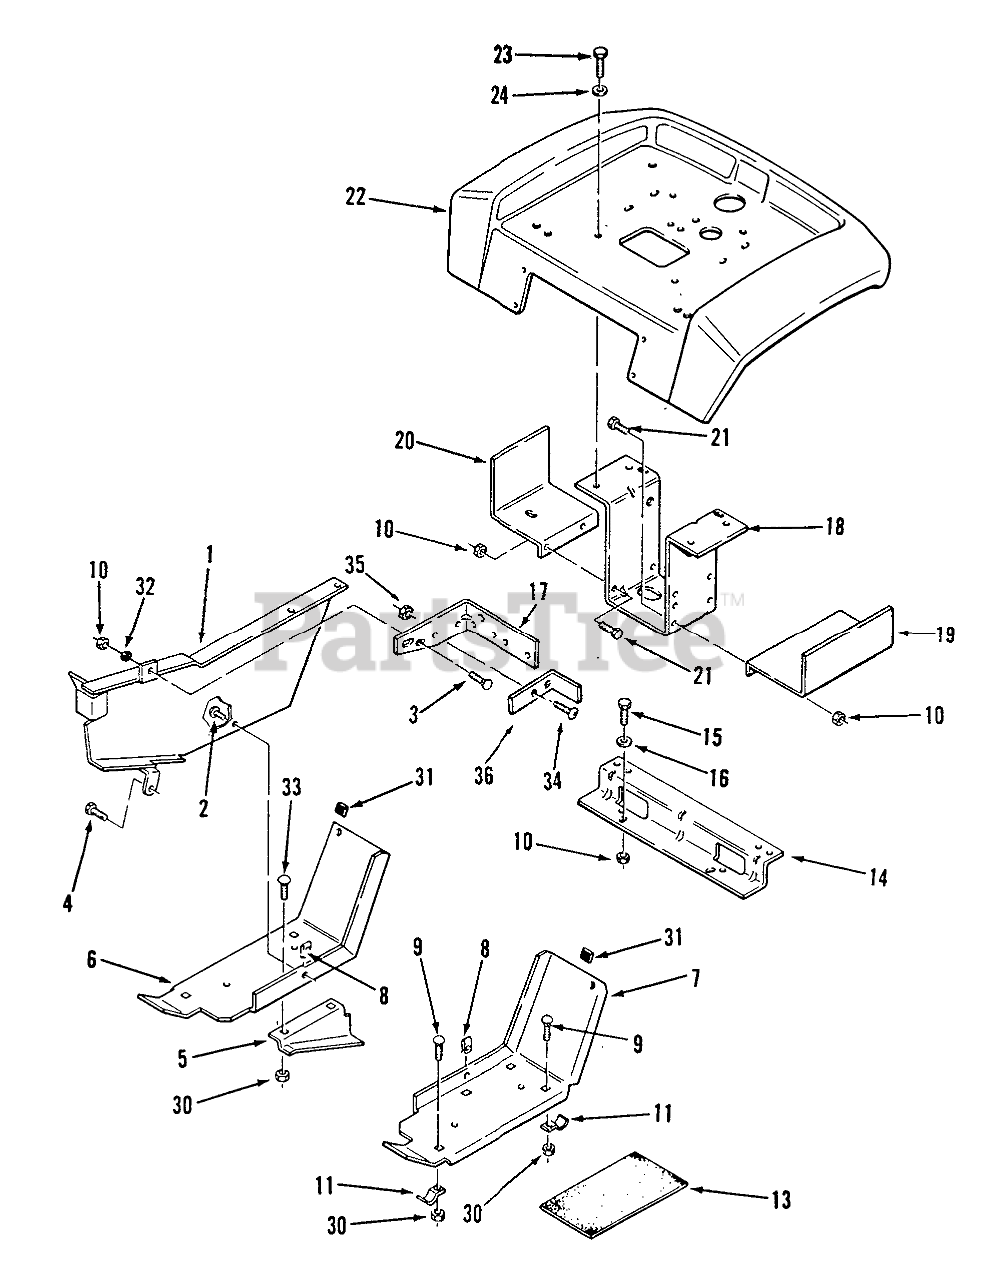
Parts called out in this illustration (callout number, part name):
1	ASSY-BELT GUARD 8 R
2	Screw
3	Bolt
4	SCREW
5	GUID-LOWER BLTR
6	Footrest-RH
7	FOOTREST LH R
9	Bolt
10	Nut
11	BRACKET
13	PAD FOOTREST
14	BRACKET-FENDER B
15	Bolt
16	WASHER 5/16 SAE
17	SUPPORT-BELT GUAR B
18	Bracket-Fender Support
19	Fuel Tank Support LH
20	Support-FueITank RH
21	Bolt
22	Fender
23	SCREW
24	WASHER 5/16 SAE
30	Nut
31	BUMPER
32	NUT-PUSH
33	Bolt-Carriage
34	HWHMS 10-24 X 5/8
35	Nut
36	BRACKET FUSE
